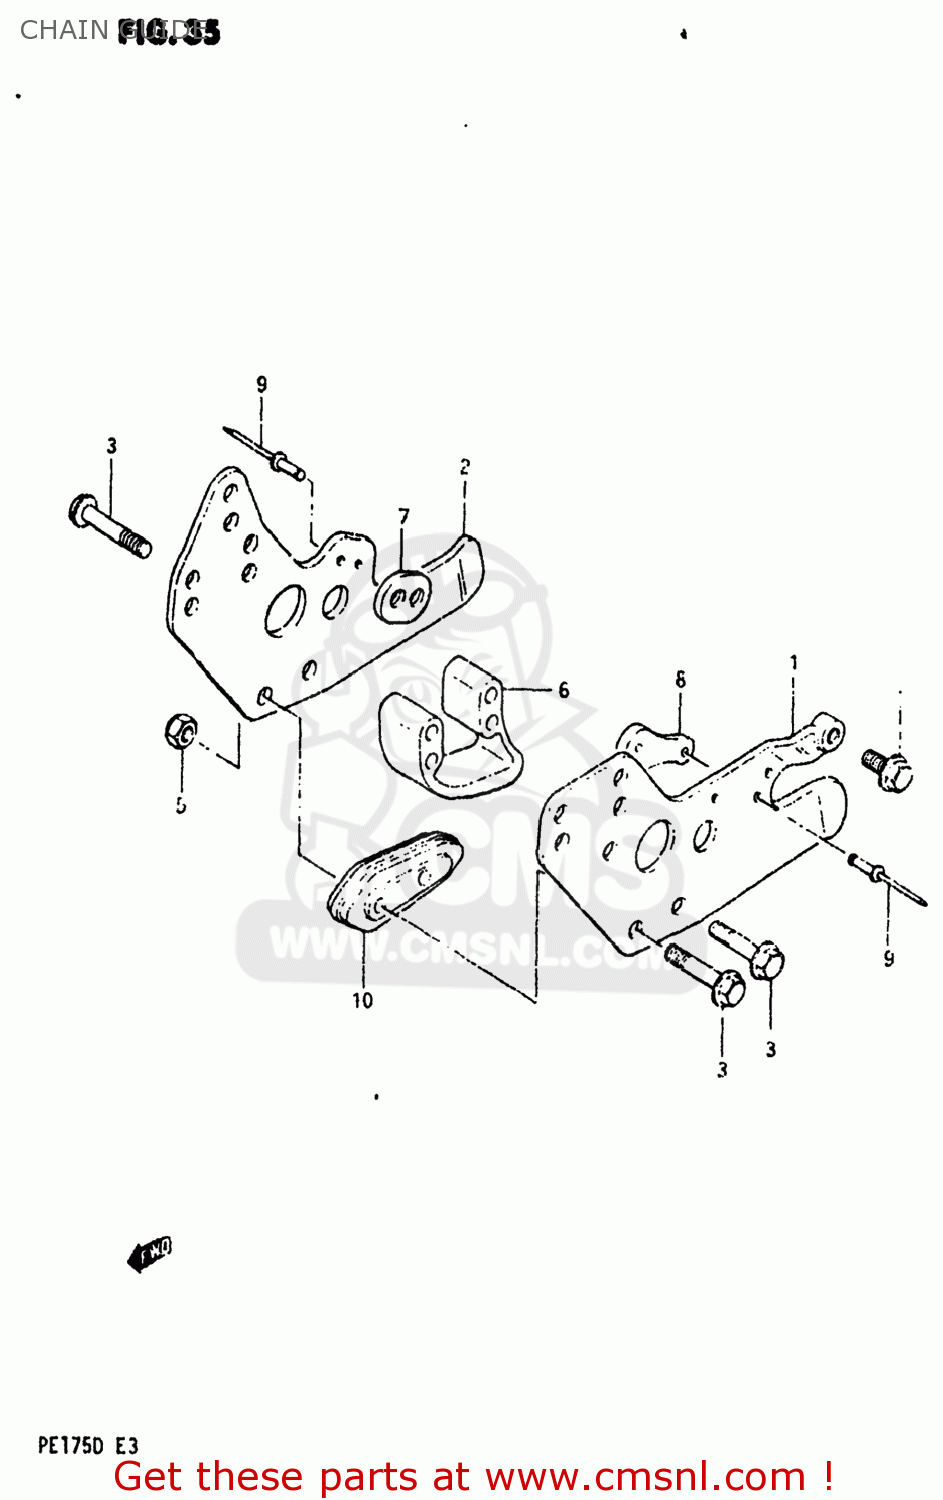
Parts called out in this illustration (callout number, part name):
1	PLATE,CHAIN GUIDE,OUTER
2	PLATE,GUIDE CHAIN
3	BOLT
4	BOLT
5	NUT
6	DEFENSE,CHAIN GUIDE,UPPER
7	PAD,DRIVE CHAIN GUIDE
8	PAD,DRIVE CHAIN GUIDE
9	RIVET
10	DEFENSE,CHAIN GUIDE
